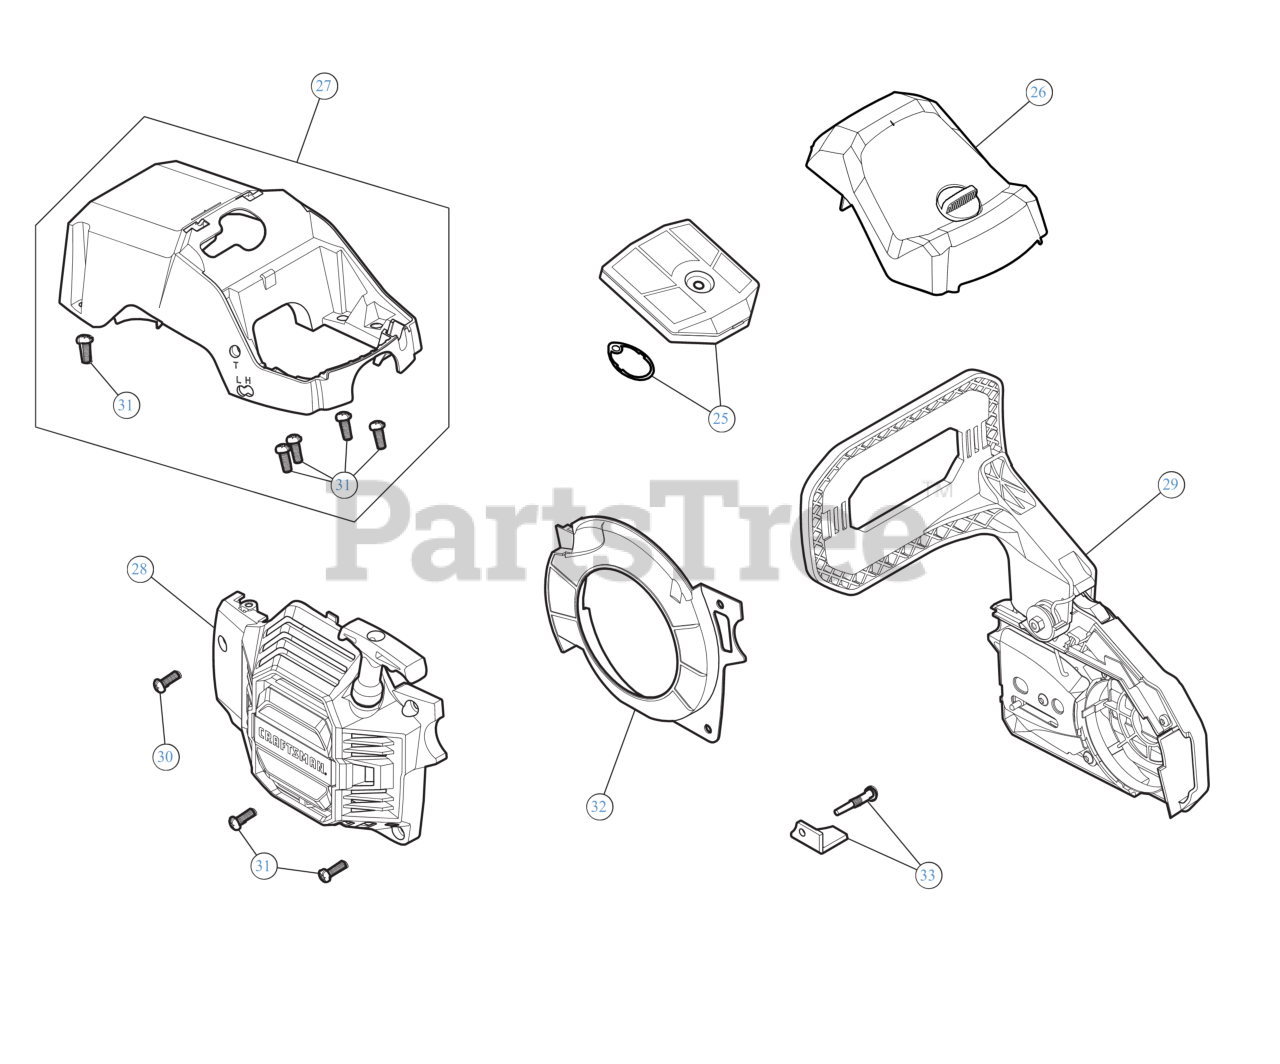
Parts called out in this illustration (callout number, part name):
25	AIR FILTER
26	AIR FILTER COVER
27	CYLINDER COVER
28	STARTER HOUSING
29	CHAINSAW BRAKE
32	BAFFLE
33	CHAIN CATCHER
